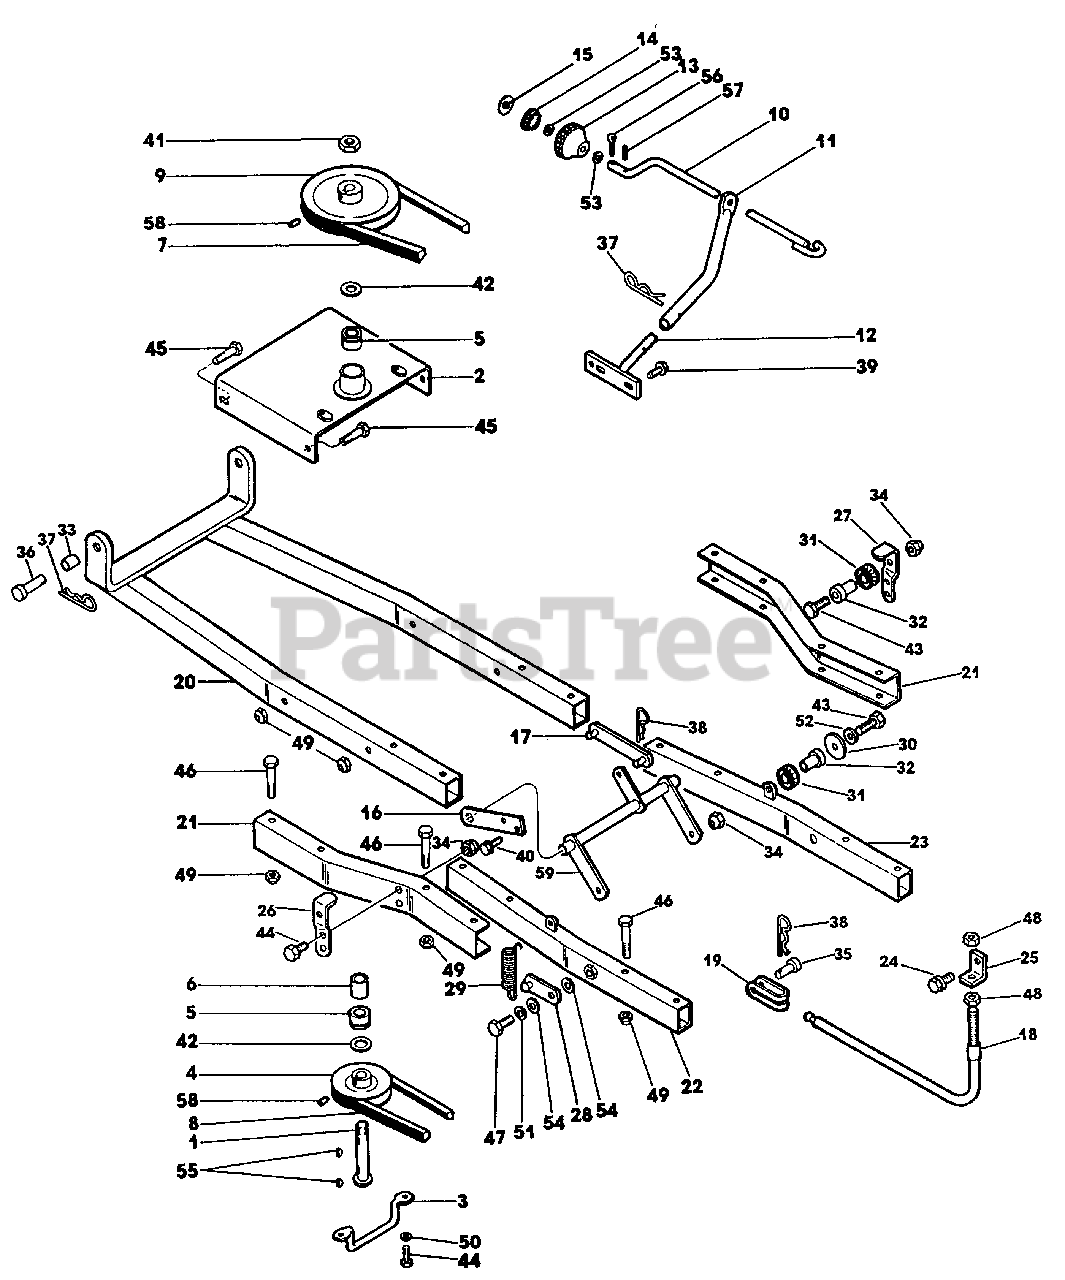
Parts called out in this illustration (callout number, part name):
1	Shaft Assembly
2	Pulley Support Assembly
3	Belt Guard
4	Pulley
5	Bearing w/Snap Ring
6	Spacer
7	V-Belt (Primary)
8	V-Belt(Secondary)
9	Pulley
10	Chute Control Assembly
11	Tube-Chute Control Support
12	Chute Control Support Assembly
13	Knob
14	Plug Button & Decal Assembly
15	Decal-Discharge Guide
16	Lift Support Arm
17	Lift Link Assembly
18	Lift Cable
19	Cable Clevis
20	Rear Frame Assembly
21	Channel-Frame Connector
22	Front Frame Assembly-R.H
23	Front Frame Assembly-L.H
24	Cap Screw
25	Cable Adjustment Bracket
26	Roller Mounting Plate-R.H
27	Roller Mounting Plate-L.H
28	Spring Adjustment Arm Assembly
29	Spring-Assist
30	Washer
31	Cable Roller
32	Spacer-Roller
33	Spacer-Gear Drive Tractor Only
34	Nut, Hex Cone Lock
35	Clevis Pin
36	Clevis Pin
37	Spring Clip
38	Spring Clip
39	Thread Forming Screw, Hex Hd
40	Thread Forming Screw, Hex Hd
41	Nut, Hex Center Lock
42	Thrust Washer
43	Cap Screw, Hex Hd
44	Cap Screw, Hex Hd
45	Cap Screw, Hex Hd
46	Cap Screw, Hex Hd
47	Cap Screw, Hex Hd
48	Nut, Hex Hd
49	Nut,HexConeLock
50	Washer, Spring Lock
51	Washer, Spring Lock
52	Washer, Flat
53	Washer, Flat SAE
54	Washer, Flat SAE
55	Key, Woodruff
56	Pin, Cotter
57	Pin, Roll
58	Set Screw, Hex Socket Hd. Cup Pt.
59	Bellcrank Assembly
